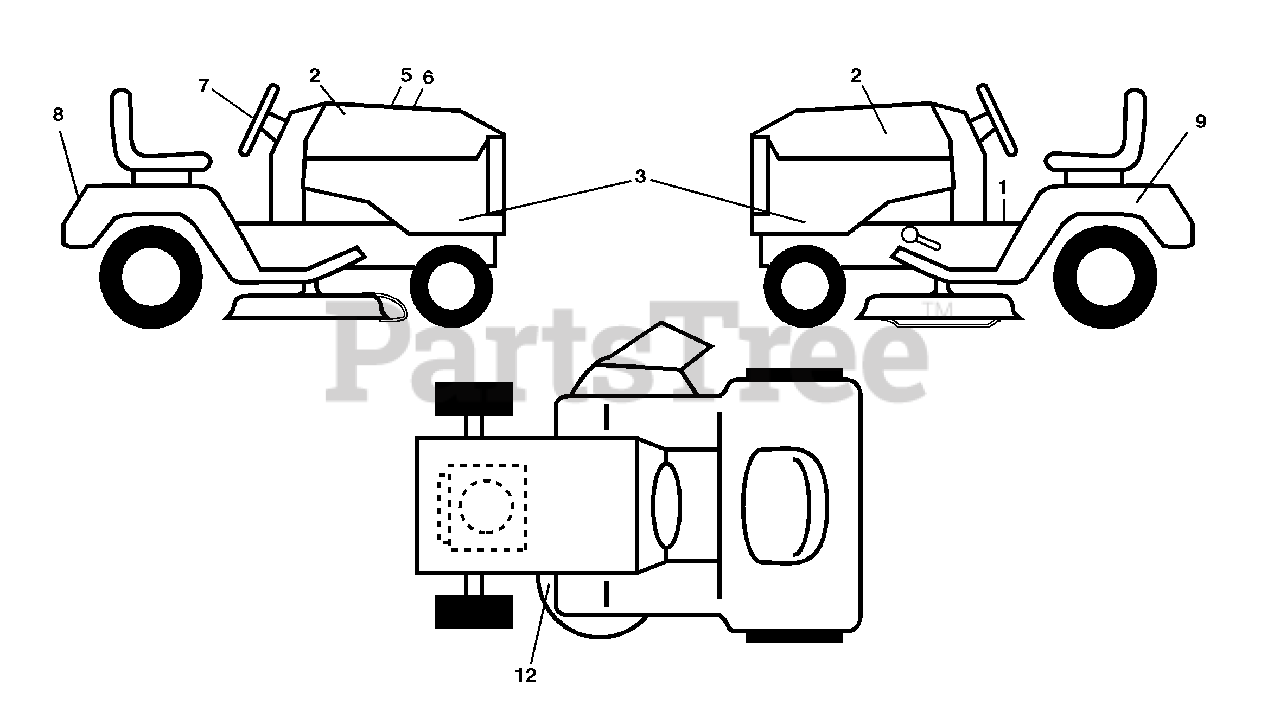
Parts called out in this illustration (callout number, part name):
1	Decal, Fender Warning
2	Decal, Hood
3	Decal, Hood Panel SD
5	Decal, Customer Respons.
6	Decal, Replacement
7	Decal, Steering Wheel
8	Decal, Fender
9	Decal, Battery Dnge/Poi
12	Decal, Mower V-Belt Schematic
12	Decal, Bypass
12	Pad, Footrest, LH
12	Pad, Footrest, RH
12	Decal, Pedal Control
12	Manual, Owner's
